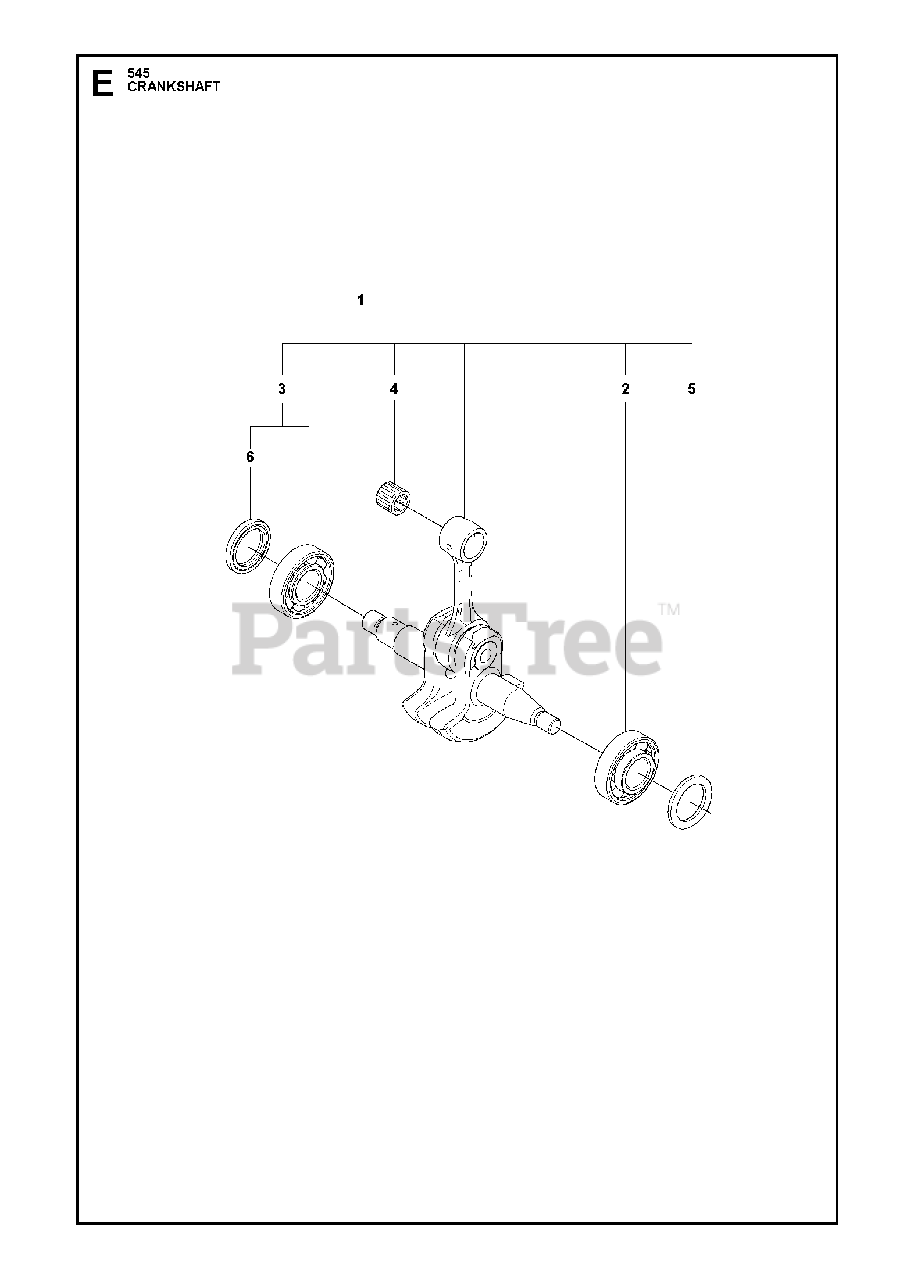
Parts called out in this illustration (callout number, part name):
1	CRANKSHAFT ASSY
2	BALL BEARING
3	BALL BEARING
4	NEEDLE BEARING
5	RADIAL SEAL
6	SEALING
